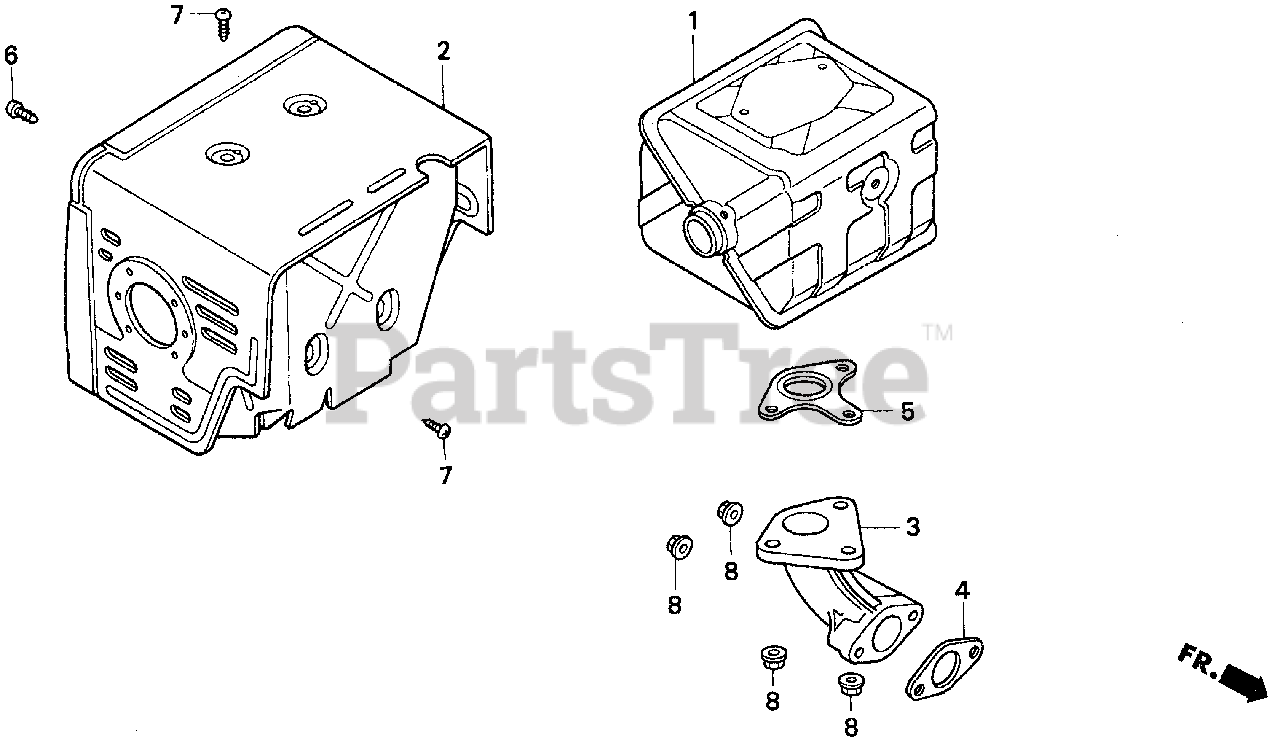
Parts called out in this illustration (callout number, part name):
1	MUFFLER (100DB) (SILENT)
1	MUFFLER (100DB)
2	PROTECTOR, MUFFLER
3	PIPE, EX.
4	GASKET, EX. PIPE
4	GASKET, EX. PIPE (WACKER)
5	GASKET, MUFFLER
6	SCREW, TAPPING (6X10)
7	SCREW, TAPPING (5X8)
8	NUT, FLANGE (8MM)
